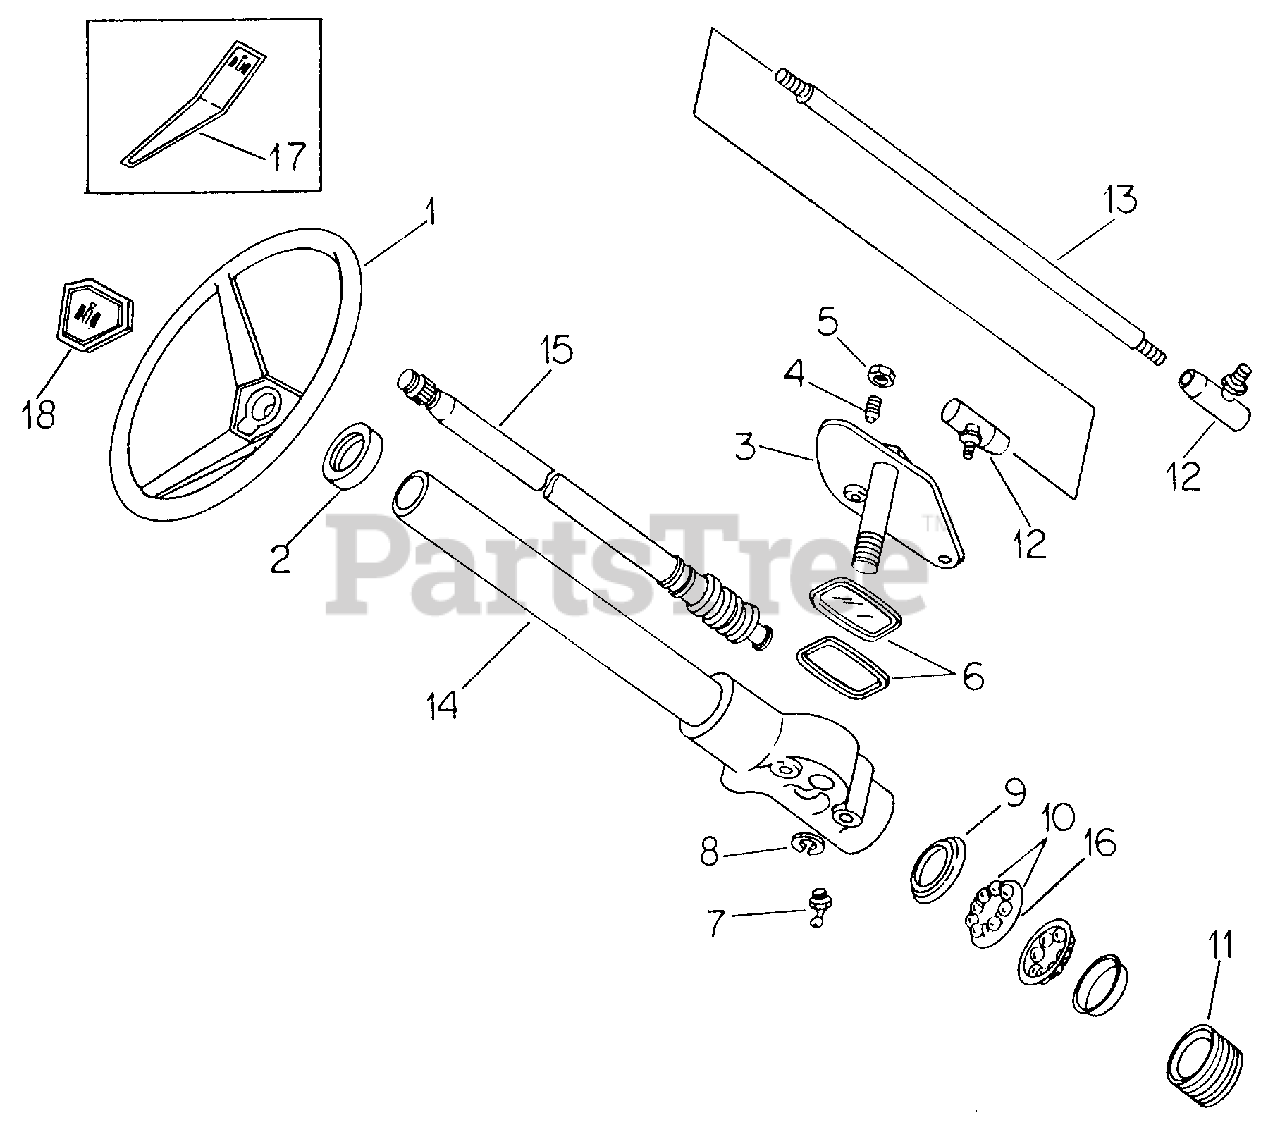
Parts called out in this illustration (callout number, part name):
1	Wheel, Steering
2	Bearing, Upper Column
3	Lever & Bolt Assy
4	Stud, Cam Follower
5	Nut, Cam Follower Stud
6	Package, Seal & Seal Retainer
7	Fitting, 1/4-65 Deg Angle Drive Lube
8	Washer, Flat Cdp
9	Cup, Bearing Ball
10	Bearing & Ball Assy
11	Plug, Adjusting
12	Joint Assy, Drag Link Ball
13	Link, Drag
14	Tube Assy, Housing & Jacket
15	Cam & Tube Assy
16	Retainer, Ball
17	Product Graphic, Steering Wheel Insert
18	Cap, Steering Wheel
